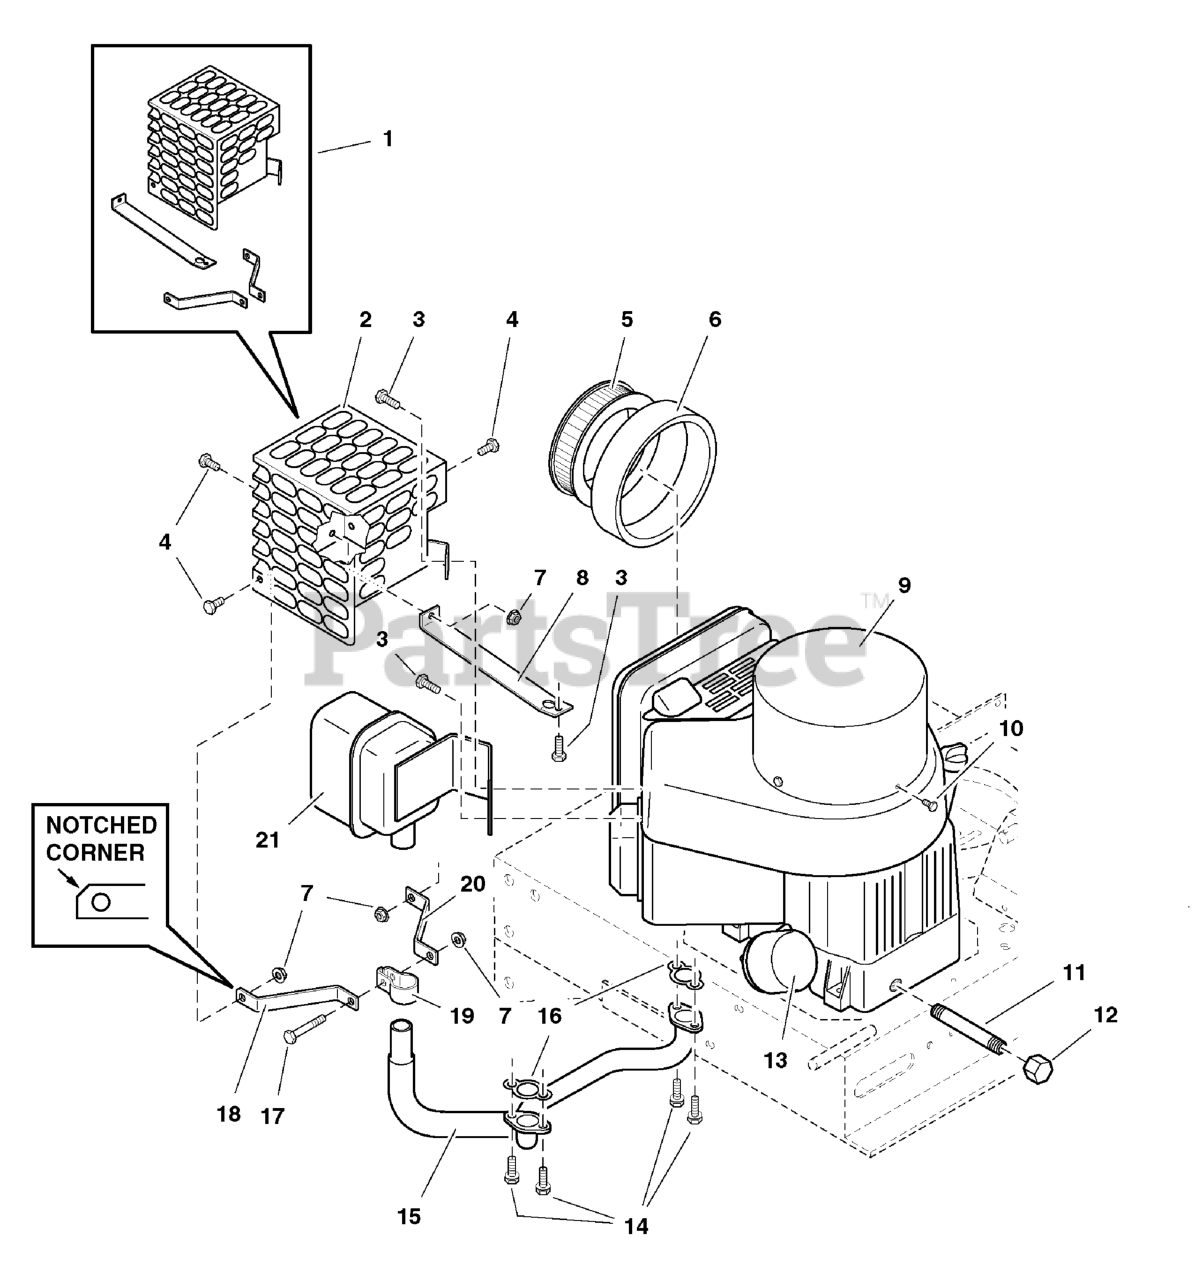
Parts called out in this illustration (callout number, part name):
1	MUFFLER GUARD ASSEMBLY, Complete
2	MUFFLER GUARD
4	BOLT, 5/16-18 X 3/4 GD5
7	NUT, 5/16-18 HEX SERRATED FLANGE (SMALL)
8	BRACKET, Bottom
11	NIPPLE, 3/8 NPT x 4-1/2
12	CAP, 3/8 NPT
13	OIL FILTER (492932)
17	BOLT, 5/16-18 x 2
18	BRACKET, Front, Left
20	BRACKET, Front-Right
